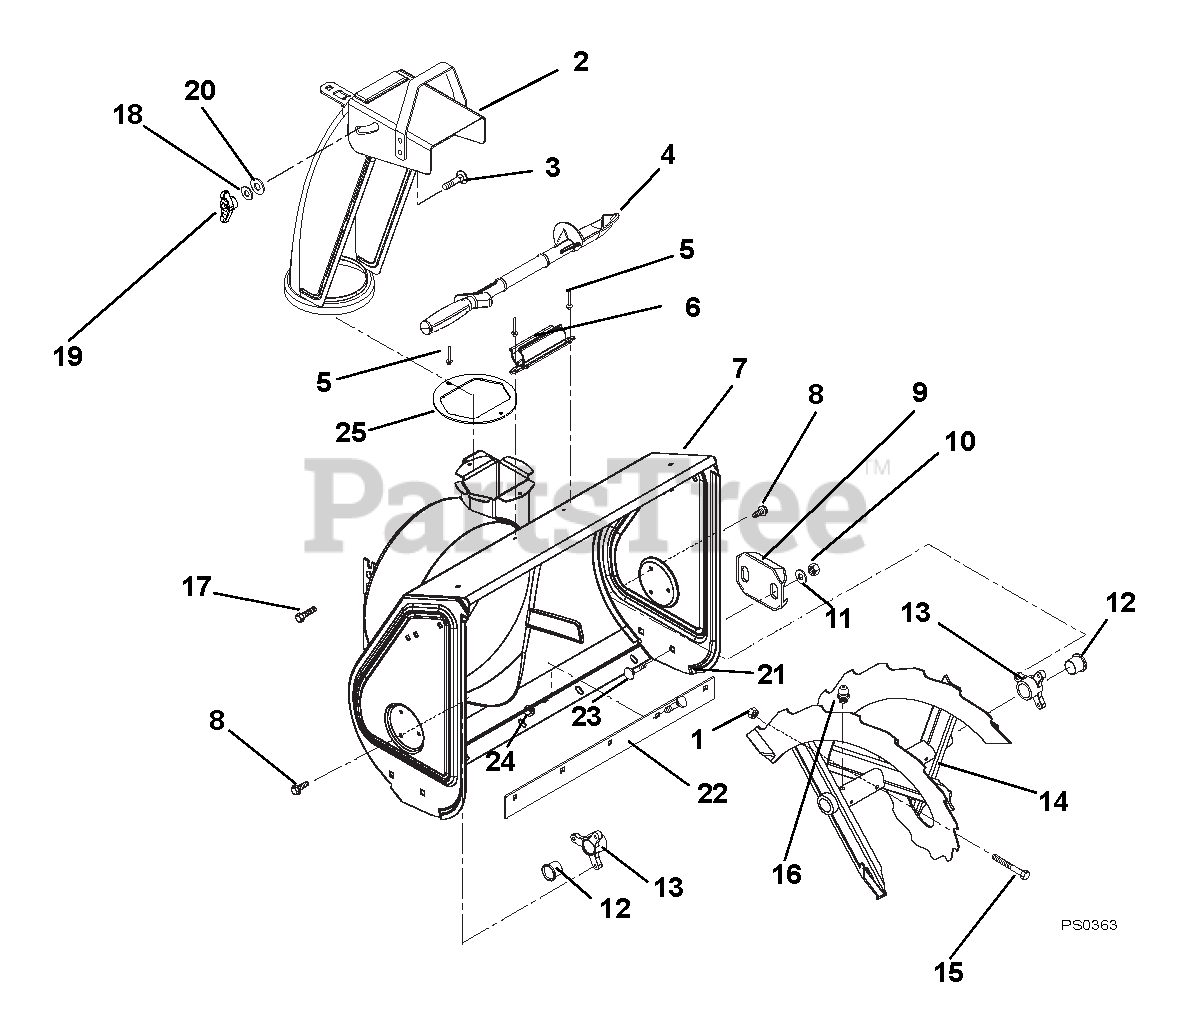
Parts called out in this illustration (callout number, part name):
1	@NUT-LK-CTR .25-20 YWZC
2	CHUTE, DISCHARGE W/CAP & DECAL
3	@BLT-RHDSSQNK .31-18X1.00 G5YZ
4	DEVICE, SNOW CLEAN OUT
5	RVT-POP .187 YZ
6	MOUNT, SNOW CLEAN OUT
7	BLOWER HOUSING, 24" HI ORANGE
8	SCR-TAP .25-20X.50 HWH TR YWZ
9	SKID SHOE, REVERSIBLE - ORANGE
10	@NUT-LK-CTR .38-16 YWZC
11	@WSHR-FL-STL.38X.875X.083 YWZC
12	BSHG-FLG SPLIT NYLINER .75"ID
13	BUSHING, RAKE SHAFT .75"
14	RAKE, 24" RH, BLK SERR W/ZERK
15	SHEAR BOLT WITH NUT
16	ZERK,FITTING .25X.125 DRIVE IN
17	@SCR-TAP .31-18X.50 HWH TR YWZ
18	@WSHR-FL-STL.344X.688X.065YWZC
19	KNOB,WING .31-18 UNC NYL/TALC
20	WSHR-FL-NY .375X.75X.060
21	BLT,RDSHHDSQSHNK .31-18X.62 YZ
22	SCRAPER BLADE, 24" COMPACT HI
23	@BLT-RHDSSQNK .38-16X.75 G5YZ
24	@NUT-LK-TOP-FLG .31-18 YWZC
25	BAFFLE, COMPACT DISCHARGE
